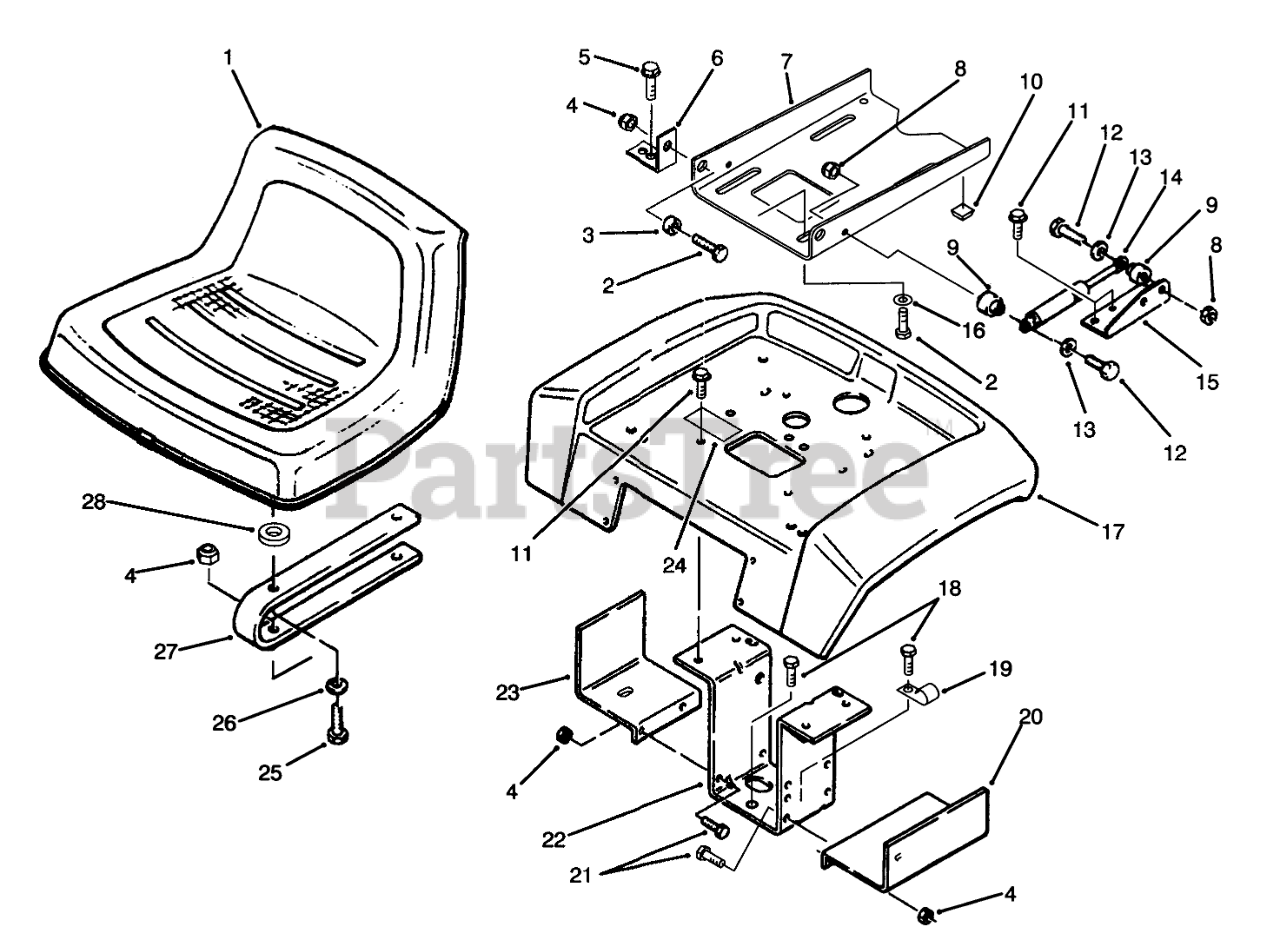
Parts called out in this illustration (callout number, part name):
1	SEAT V-510
2	SCREW-HH
3	BUSHING
4	NUT-LOCK, NI
5	Bolt
6	BRACKET-PIVOT
7	Plate-SeatPivot
8	NUT-LOCK, NI
9	SPACER
10	BUMPER SJ5514 BLACK
11	SCREW
12	SCREW-HH
13	WASHER-FLAT
14	GAS SPRING
15	BRACKET-CYLINDER R
16	WASHER-PLAIN
17	Fender
18	SCREW-HH, LOCK
19	CLIP
20	Fuel Tank Support LH
21	SCREW-HH
22	Bracket-Fender
23	Support-FueITank RH
24	DECAL-DO NOT TOW
25	SCREW-HH
26	WASHER-LOCK
27	Seat Spring
28	SPACER-NYLON
